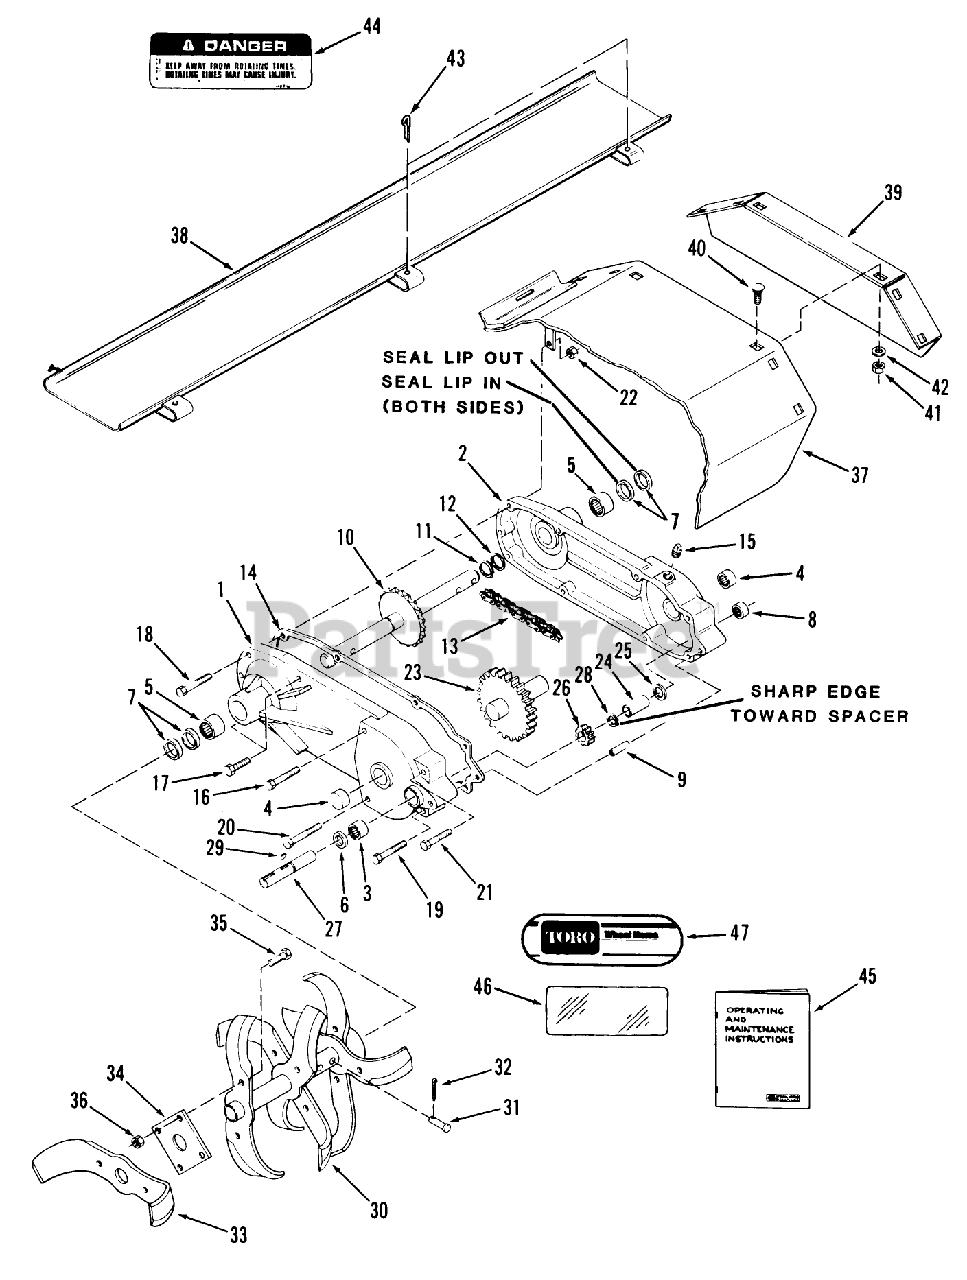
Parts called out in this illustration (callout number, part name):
1	Case
2	Case
3	BEARING-NEEDLE
4	BEARING-NEEDLE
5	BEARING-NEEDLE
6	SEAL-OIL
8	BEARING-NEEDLE
9	ROLL PIN 3/8 X 1
10	TINE SHAFT ASM
11	Snap Ring
12	WASHER
13	CHAIN
14	Gasket
15	SOLID PIPE PLUG
16	H H C S
17	Bolt
18	HHCS
19	BOLT
20	Hex Bolt
21	Bolt 3/8-16 x 3 3/4
22	NUT
23	GEAR AND SHAFT ASM
24	Spacer
25	WASHER-THRUST
26	GEAR-PINION
27	SHAFT-INPUT
28	RING-SNAP, EXTERNAL
29	Key
30	Tine R.H.
30	Tine L.H.
31	PIN-CLEVIS
33	R.H. Tine
33	L.H. Tine
34	Plate-Tine Mounting
35	H H C S
36	Nut
37	X-REF 92-6514-01
38	Rear Shield
39	Cover-End
40	CARRIAGE BOLT -4
41	Nut
42	WASHER 5/16 SAE
44	Decal-DANGER
45	Operating Maintenance Instructions
46	DECAL-OVERLAY
47	Decal
